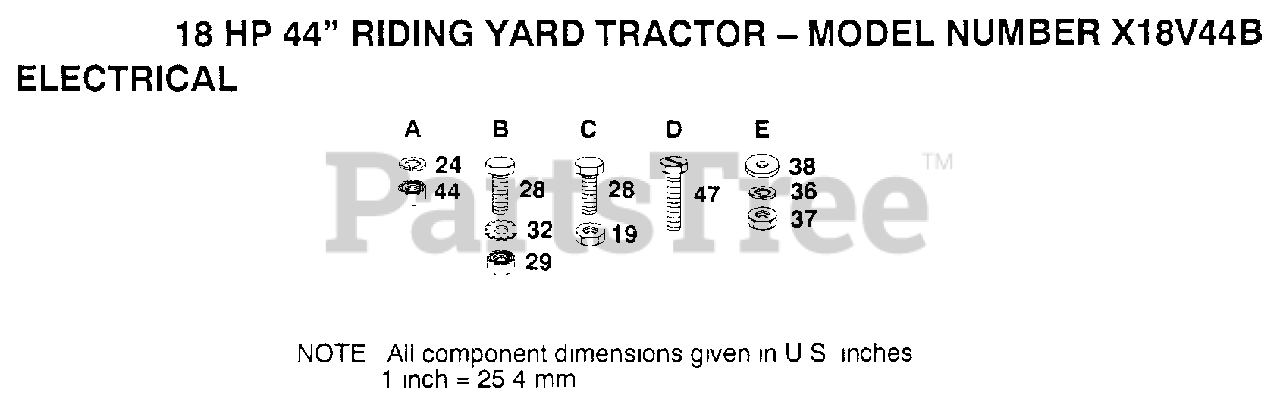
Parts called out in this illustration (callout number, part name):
28	BOLT
29	NUT
38	WASHER
44	NUT
47	SCREW
